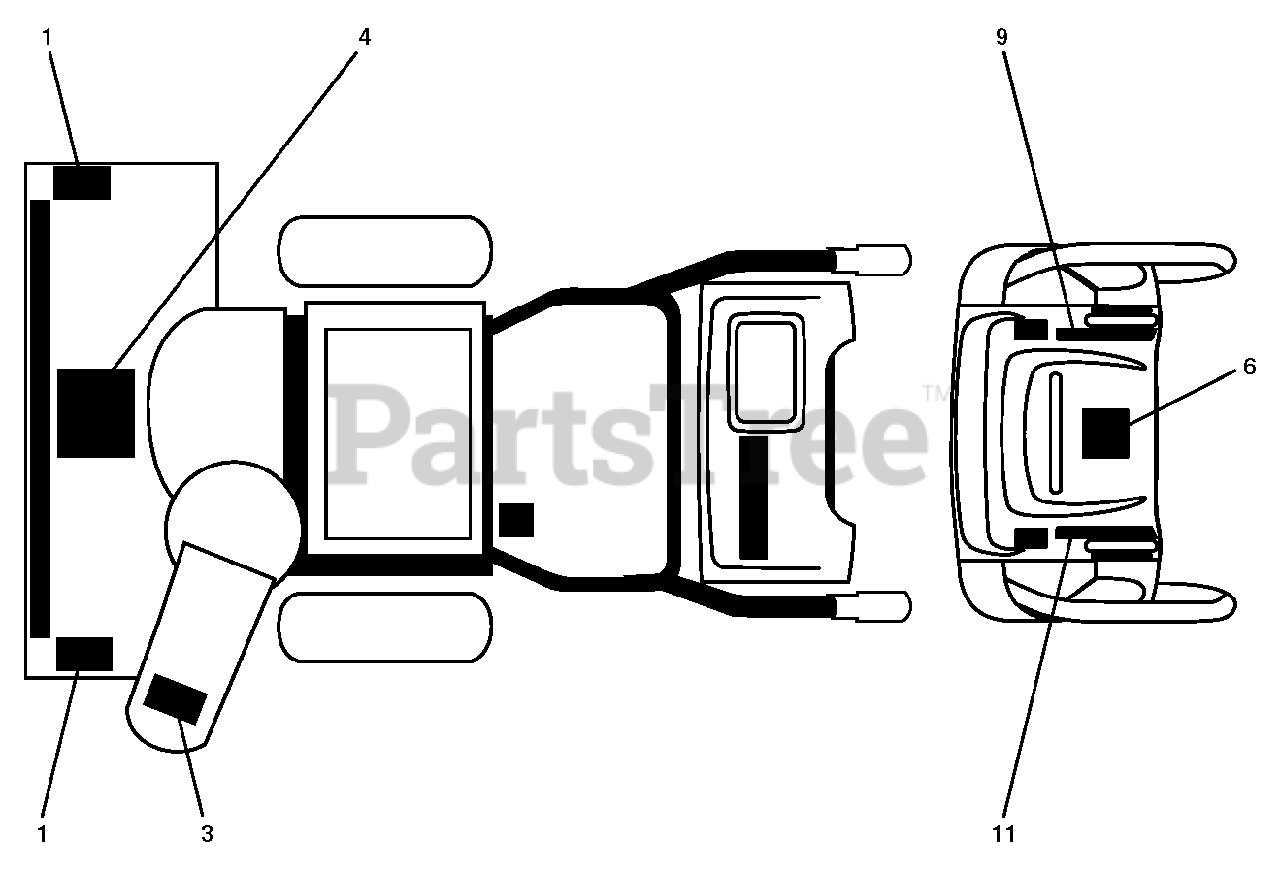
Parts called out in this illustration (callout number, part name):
1	DECAL.SNOWTHR.AUGER
3	DECAL.SNOWTHR.CHUTE.SAFETY
4	DECAL.SNOWTR.READ.OWN.MAN.E/F
6	DECAL.CONSOLE.SNOW.INST.ENG/FR
9	DECAL.CONS.RT.SPD/LEV/PWRST.
11	DECAL.CONS.LT.SPD/LEV/PWRST.
12	DECAL.CONSOLE.HAND.WARMER
